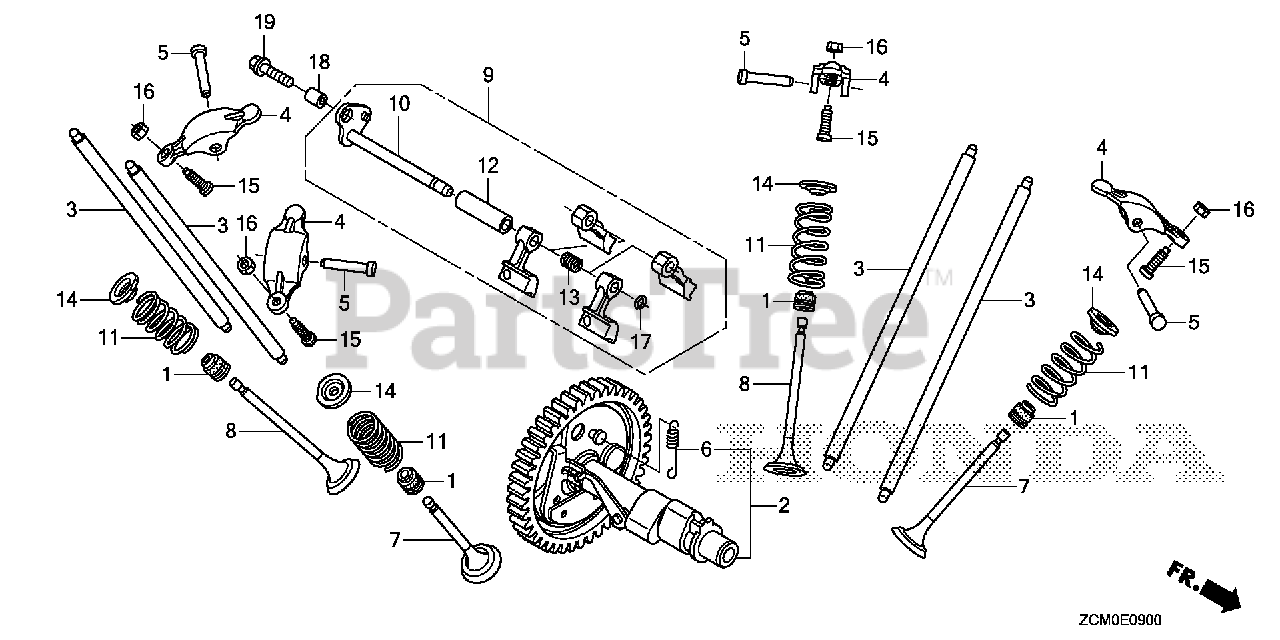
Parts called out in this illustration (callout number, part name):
1	SEAL, VALVE STEM
2	CAMSHAFT ASSY.
4	ARM, VALVE ROCKER
5	SHAFT, ROCKER ARM
6	SPRING, WEIGHT RETURN
7	VALVE, IN.
8	VALVE, EX.
9	LIFTER ASSY., VALVE
10	SHAFT, VALVE LIFTER
11	SPRING, VALVE
12	COLLAR, VALVE LIFTER
13	SPRING, VALVE LIFTER
14	RETAINER, IN. VALVE SPRING (IN./EX.)
14	RETAINER, VALVE SPRING
15	SCREW, TAPPET ADJUSTING
16	NUT, TAPPET ADJUSTING
17	CLIP, GOVERNOR HOLDER
18	PIN, DOWEL (8X10)
19	BOLT, FLANGE (6X22)
